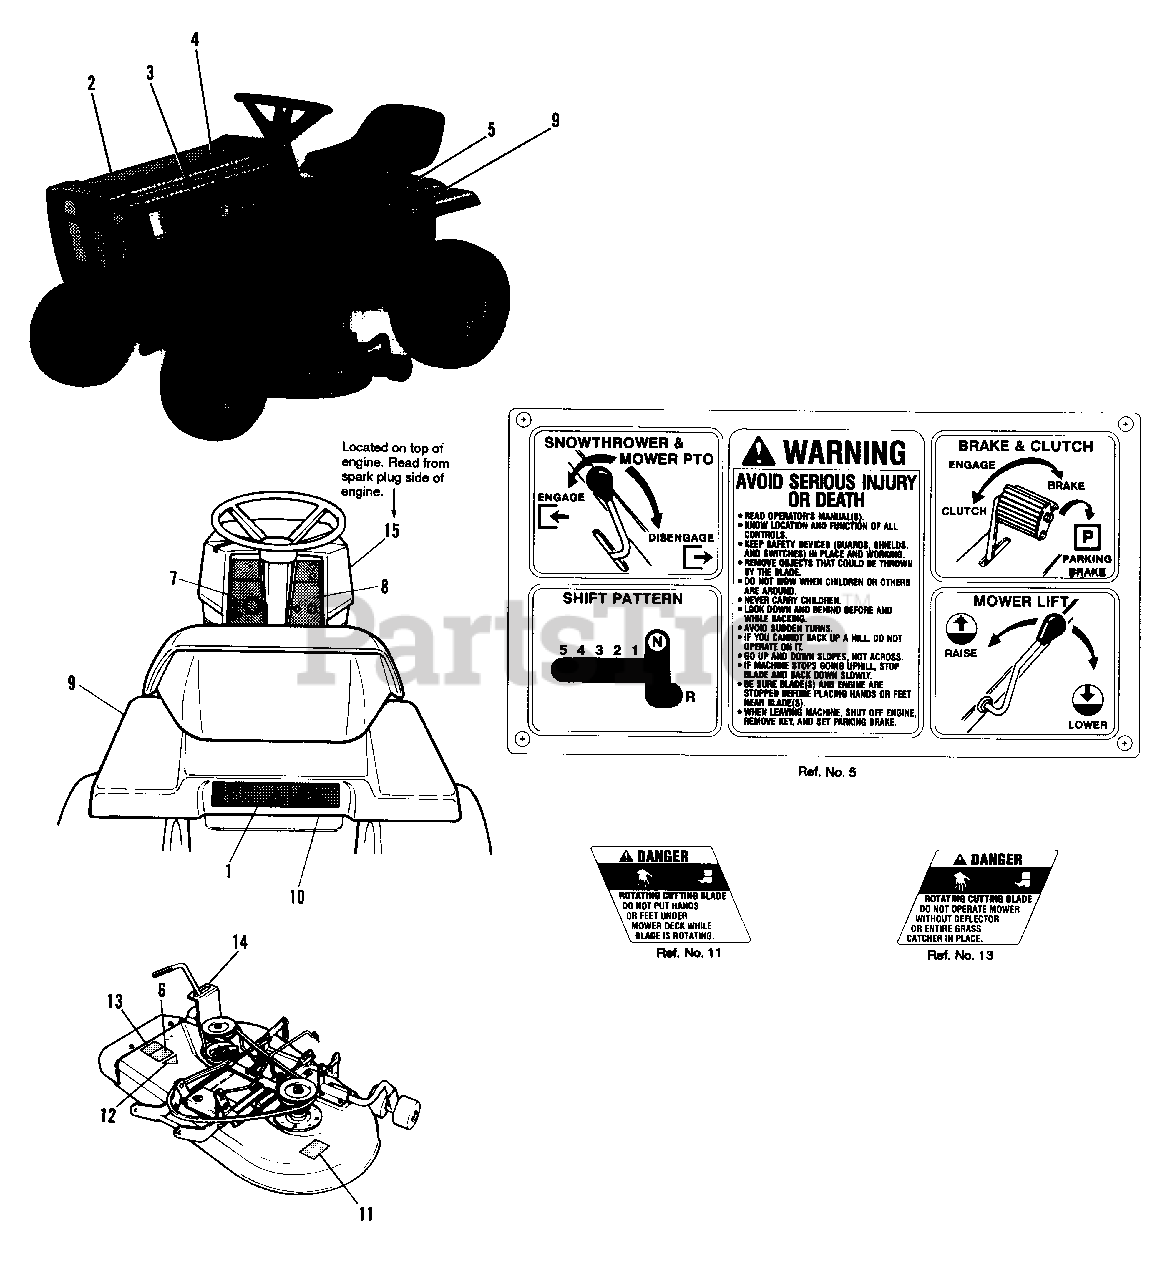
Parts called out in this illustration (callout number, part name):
1	DECAL, Simplicity
2	DECAL, Hood, R.H.
3	DECAL, Hood, L.H.
4	DECAL, Drive Belt (used on 1692049 only)
4	DECAL, Drive Belt (used on 1692094 only)
5	DECAL, Shift Pattern
6	DECAL, Cutting Width, 36"
7	DECAL, Dash, L.H. Side
8	DECAL, Dash, R.H. Side
9	DECAL, 12 RTG
10	DECAL, Battery
11	DECAL, Danger, Rotating Blade
12	DECAL, OPEI
13	DECAL, Danger, Deflector in Place
14	DECAL, Mower Height
15	DECAL, Simplicity 12 HP, I/C
